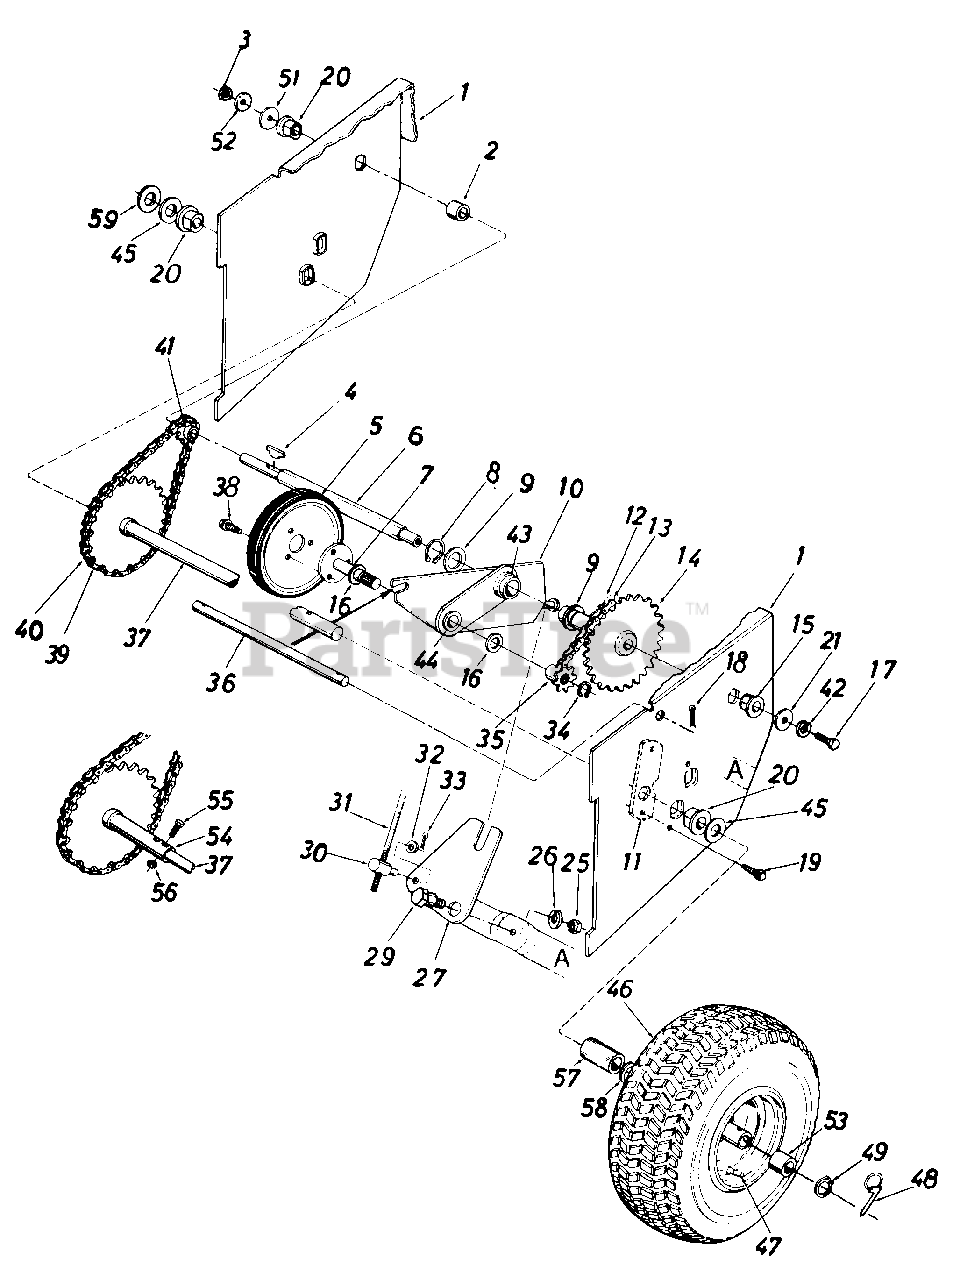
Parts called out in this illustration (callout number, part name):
1	Frame Ass'y.
2	Spacer.50" I.D. x .75" O.D. x.78" Lg.
3	Hex Ins. L-Nut 1/2-20 Thd.
4	#4 Hi-Pro Key 3/32 x 5/8" Dia.
5	Friction Wheel Ass'y.
6	Hex Shaft
7	Friction Wheel Mounting Plate Ass'y.
8	Snap Ring 1.00" Dia. Shaft
9	Fl-Wash. 1.00" x 1.63" O.D. x .03
10	Sliding Bracket Ass'y.
11	Axle Plate 1.75" x 3/16"
12	#41 Chain 1/2" Pitch x 35 Links
13	Master Link for #41 Chain
14	32 Teeth Sprocket Ass'y.
15	Hex Flange Brg. .630" I.D.
16	Fl-Wash. .62" I.D. x 1.00" O.D. x .06
17	Hex Lock Bolt 5/16-18 x .62" Lg.
18	Cotter Pin 3/32" Dia. x .75" Lg.
19	Hex Self-Tap Scr. 5/16-24 x .5" Lg.
20	Hex Flange Brg. .751" I.D.
21	Fl-Wash. .34" I.D. x 1.12" O.D. x .125
25	Hex Jam Nut 3/8-16 Thd.
26	L-Wash. 3/8" I.D.
27	Shifting Linkage Bracket
29	Shld. Bolt .625" Dia. x .170" Lg.
30	AdJustment Ferrule
31	Shifting Rod 5/16" Dia. x 32.50" Lg .
32	Fl-Wash. .34" I.D. x .64" O.D. x .06
33	Cotter Pin 3/32" Dia. x .75" Lg.
34	Snap Ring .562" Dia. Shaft
35	Sprocket 7 Teeth x .50" Pitch
36	Shaft .50" Dia. x 9.50" Lg.
37	32 Teeth Wheel Axle Ass'y.
38	Hex Wash. Hd. Self-Tap Scr. 5/16-24 x .50" Lg.
39	#420 Chain 1/2" Pitch x 35 Links
40	Master Link for #420 Chain
41	8 Teeth Center Sprocket
42	L-Wash. 5/16" I.D.
43	Bearing
44	Bronze Bearing
45	Fl-Wash. .76" I.D. x 1.49 O.D.
46	Wheel Assembly
47	Air Valve
48	Klick Pin
49	Snap Ring .75 Dia.
51	Fl-Wash. .53 I.D. x 1.25 O.D. x . 1 0
52	Bell-Wash. .50 I.D. x 1.0 O.D. x .075
53	Sleeve Brg.
54	30 Teeth Sprocket Hub Ass'y.
55	Hex Bolt 1/4-28 x 1.5"
56	Hex L-Nut 1/4-28 Thd.
57	Spacer .75" I.D.
58	Fl-Wash. .793" I.D.
59	Fl-Wash. .76" I.D. x 1.49" O.D.
